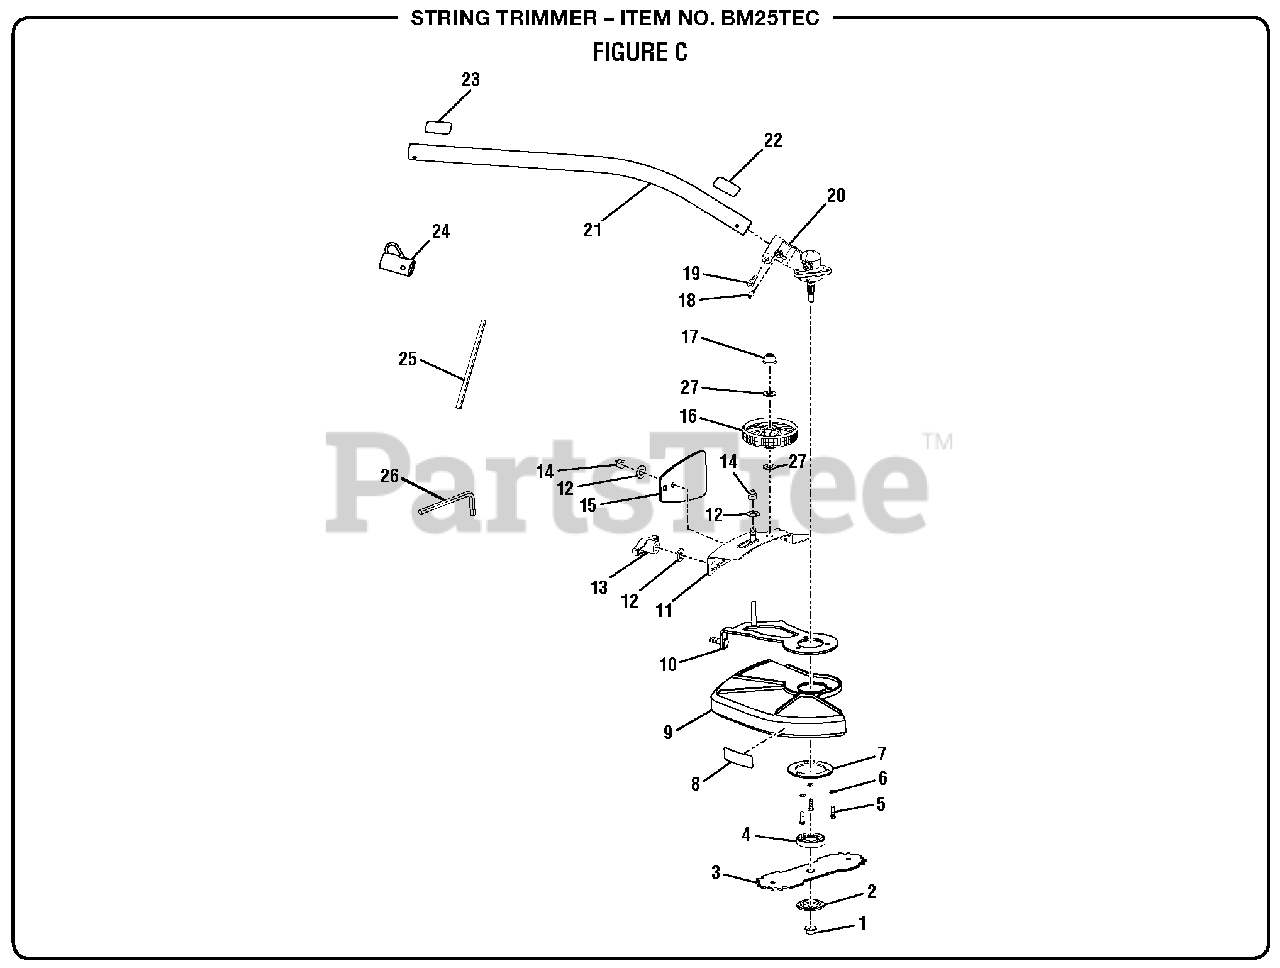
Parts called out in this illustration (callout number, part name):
1	Blade Nut (M8, Left Hand Threads)
2	Cupped Washer
4	Flanged Washer
5	Screw (10-24 x 5/8in. Hex Hd.)
6	Lock Washer (5 mm)
7	Ring Washer
8	Warning Decal
9	Blade Guard
10	Main Frame
11	Wheel Frame
12	Washer (10 mm)
13	Adjusting Knob w/Hex Nut
14	Hex Nut w/Nylon Cap (5/16-18)
15	Debris Flap
16	Guide Wheel
17	Push Nut
18	Screw (10-24 x 5/8 in., Hex Soc. Hd.)
19	Screw (1/4-20 x 1-1/4 in., Hex Soc. Hd.)
20	Gear Head Assembly
21	Drive Shaft Assembly
22	Hot Warning Label
23	Warning Label
24	Hanger Cap
25	Holding Pin
26	Hex Key (M4)
27	Washer (ID11 x OD 18 x 2t)
